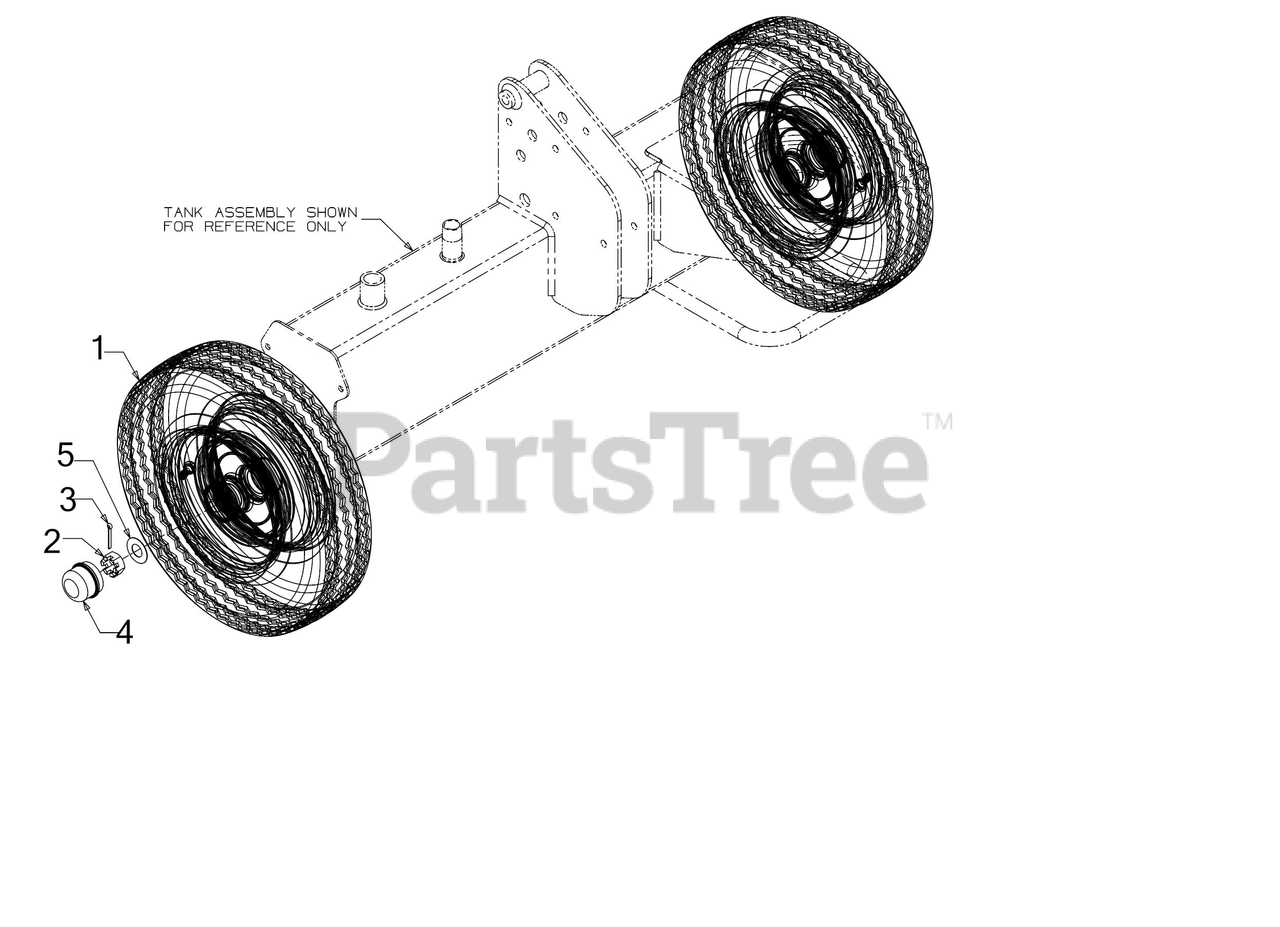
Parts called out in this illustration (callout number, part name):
1	WHEEL ASSEMBLY (16 x 4.8 x 8) (BEIGE)
2	HEX NUT CASTLE 3/4-16
3	COTTER PIN-5/32 DIA
5	THRUST WASHER
